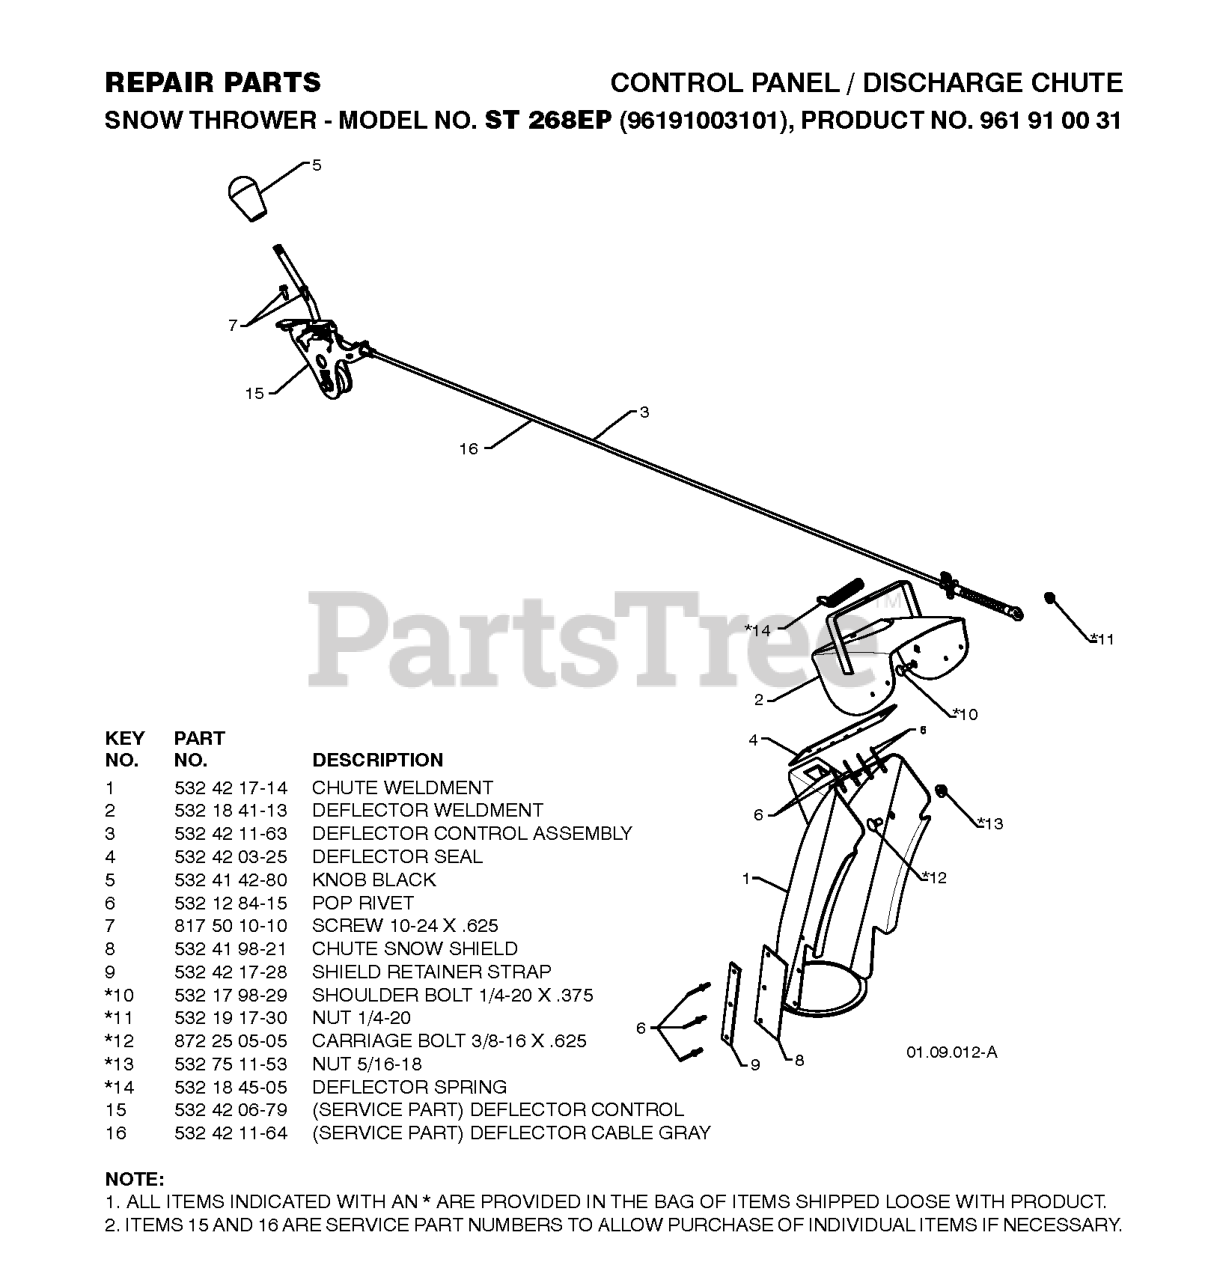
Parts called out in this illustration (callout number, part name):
1	CHUTE.WELDMENT
2	DEFLECTOR.WELDMENT.PNT.ORANGE
3	CONTROL.ASM.DEFLECTOR
4	SEAL.DEFLECTOR
5	KNOB LEVER, BLACK
6	RIVET BLIND
7	SCREW #10-24 X 5/8
8	SHIELD.SNOW.CHUTE
9	STRAP.SHEILD.RETAINER
10	BOLT, SHOULDER
11	NUT.HEX.FLANGE.1/4
12	BOLT
13	NUT.LOCK.5/16-18
14	SPRING.DEFLECTOR.REM.CHUTE
15	RP CNTRL.HEAD.ASSEM.DEFLECTOR
16	SERVICE.CHUTE.DEF.CBL.GRY
